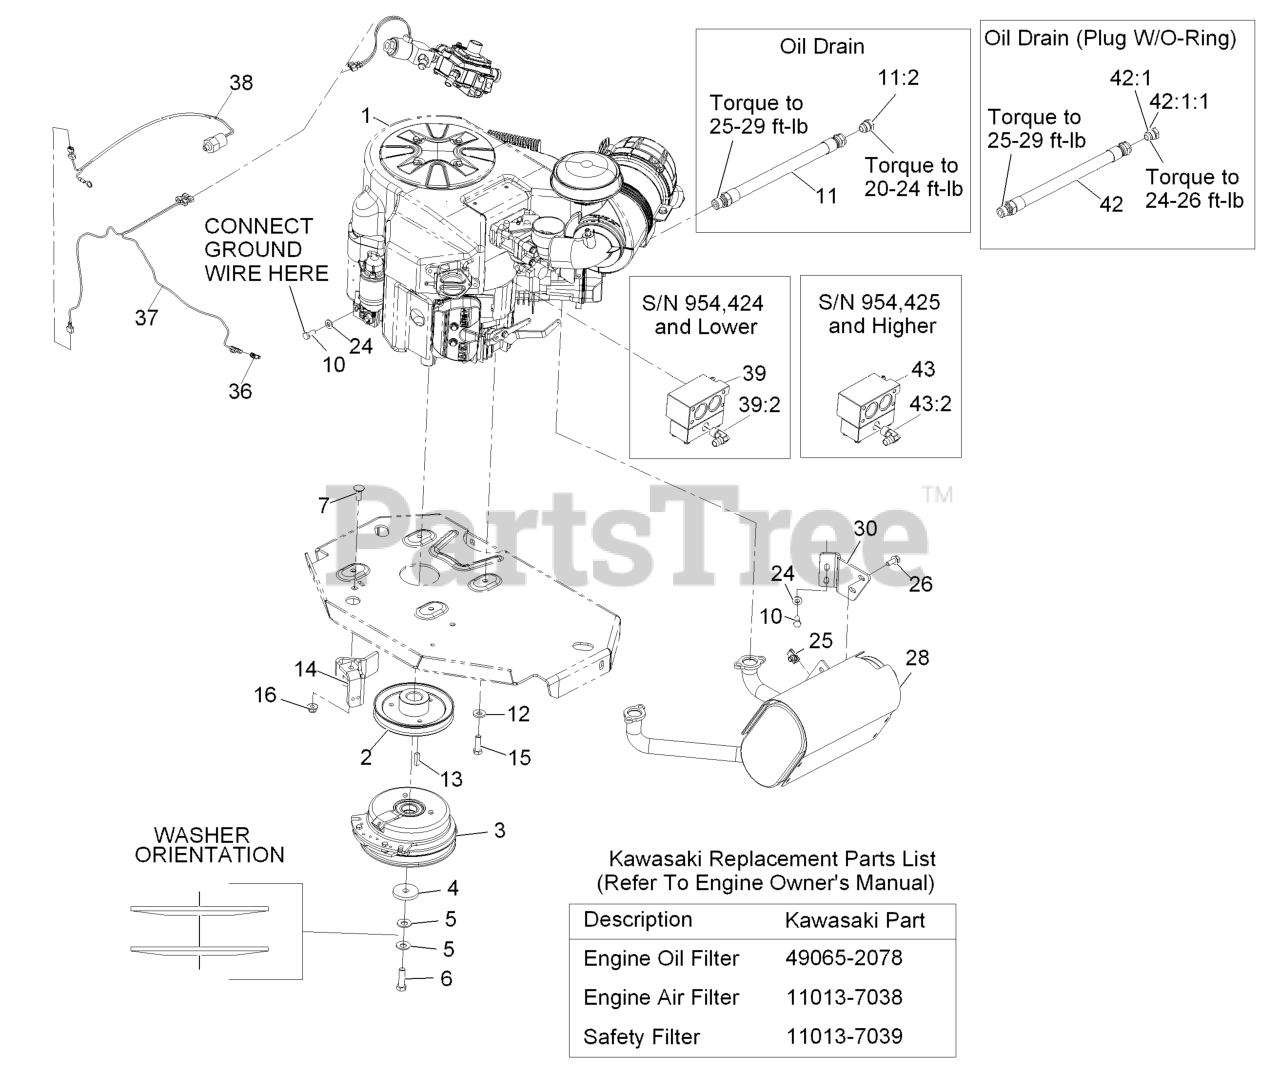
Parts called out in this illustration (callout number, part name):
2	SHEAVE
3	CLUTCH KIT
4	WASHER-CLUTCH
5	WASHER-SPRING
6	SCREW-HH 7/16-20 X 1 1/2 W/LOCTITE
7	SCREW-CARR
10	SCREW-HH
12	WASHER-BELLEVILLE
14	CLUTCH-ANCHOR
15	SCREW-HH
16	NUT-HF, NI
24	WASHER-SPRING
26	SCREW-HHF
28	MUFFLER
30	BRACKET-MUFFLER
36	TERMINAL-TAB
37	WIRE HARNESS
39	MIXER ASM
39:2	ELBOW-90 DEG
42	ENGINE OIL DRAIN HOSE ASM
42:1	PLUG-HH
42:1:1	O-RING
43	LPG MIXER ASM
